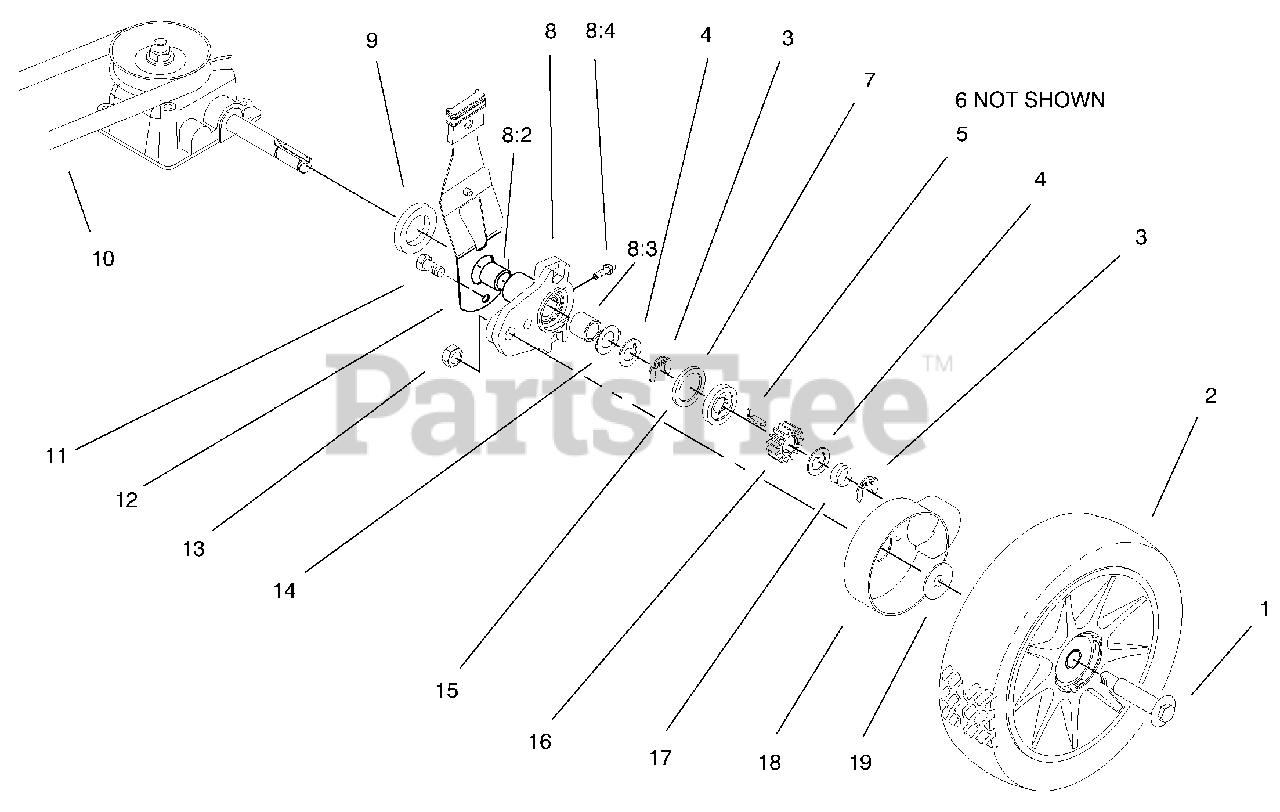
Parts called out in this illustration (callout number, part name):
1	Bolt-Shoulder
3	Ring-Retaining
4	Washer-Thrust
5	Key-Rocking LH
6	Key-Locking RH
7	Ring-Friction
8	ASM-Hgt Adj Arm
8:4	Fitting-Grease
9	Spacer-Axle Shaft
12	ASM-Spring Arm
13	Nut-Lock
14	Washer-Thrust
16	Gear-Pinion
17	Spring-Compression
18	Cover-Wheel
19	Washer-Stepped
